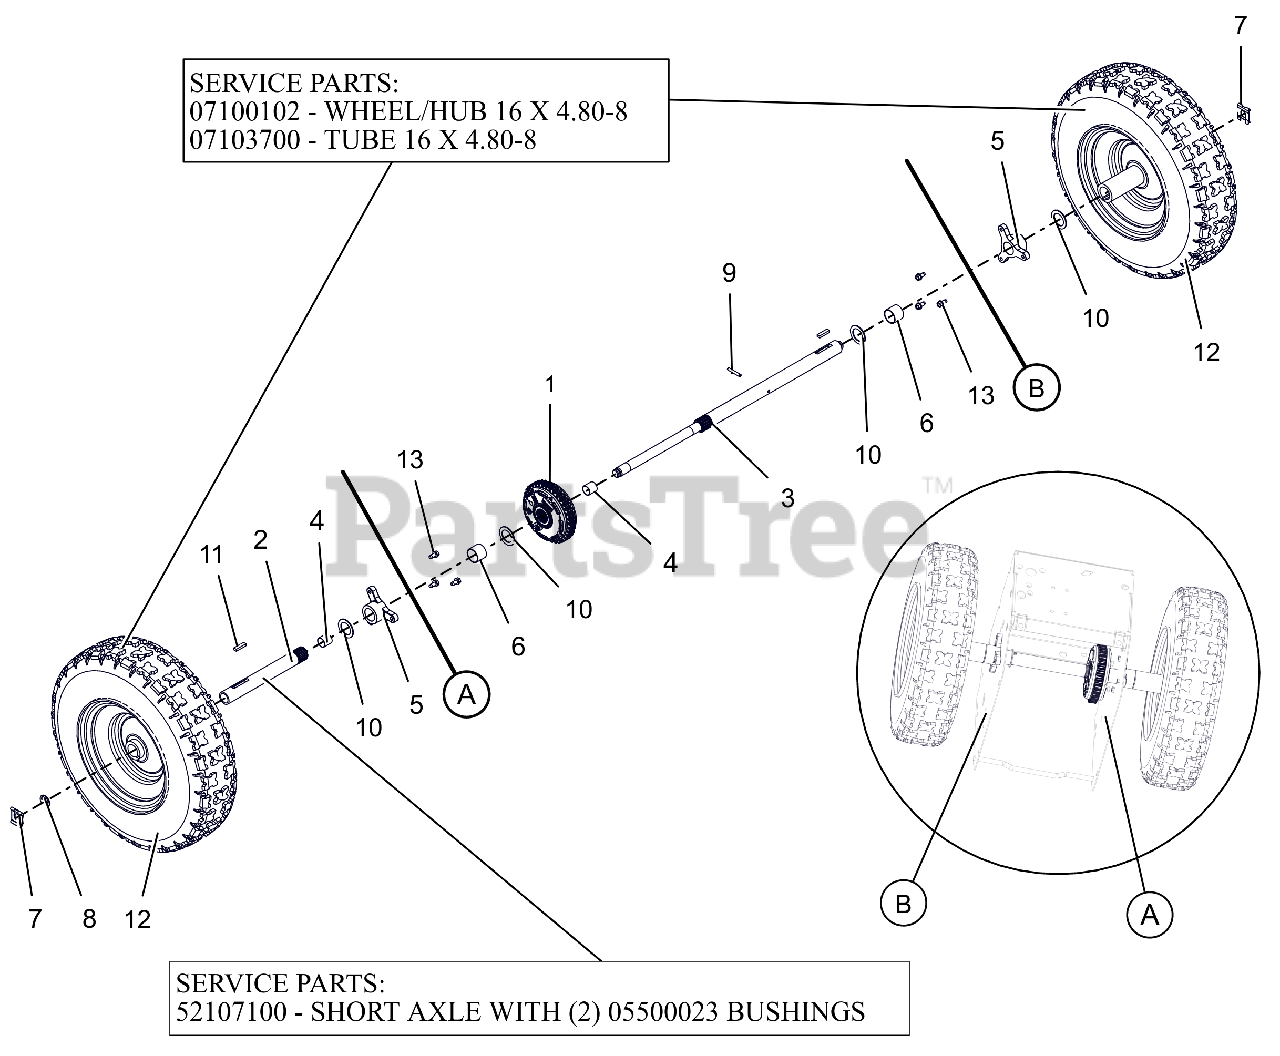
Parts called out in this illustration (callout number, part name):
1	DIFFERENTIAL, AUTOMATIC
2	KIT, SHORT AXLE W/BUSHINGS
3	AXLE, LONG - DIFFERENTIAL
4	BSHG-SLV .706X.764X.75 BRZ
5	BUSHING, AXLE
6	BSHG-SLV, 1.012X1.125X.875
7	CLIP, SNAP .625 DIA
8	RG-RTNG-EXT .625X.042
9	PIN-ROLL .188X1.25
10	WSHR-FL-STL 1.010X1.505X.062YZ
11	KEY-RECT .25X.188X1.00
12	TIRE/WHEEL,16X4.80-8 POLAR TRK
12	HUB, WHEEL - 16X4.8-8 DIFF
12	TUBE
13	SCR-TAP .25-20X.50 HWH TR YWZ
